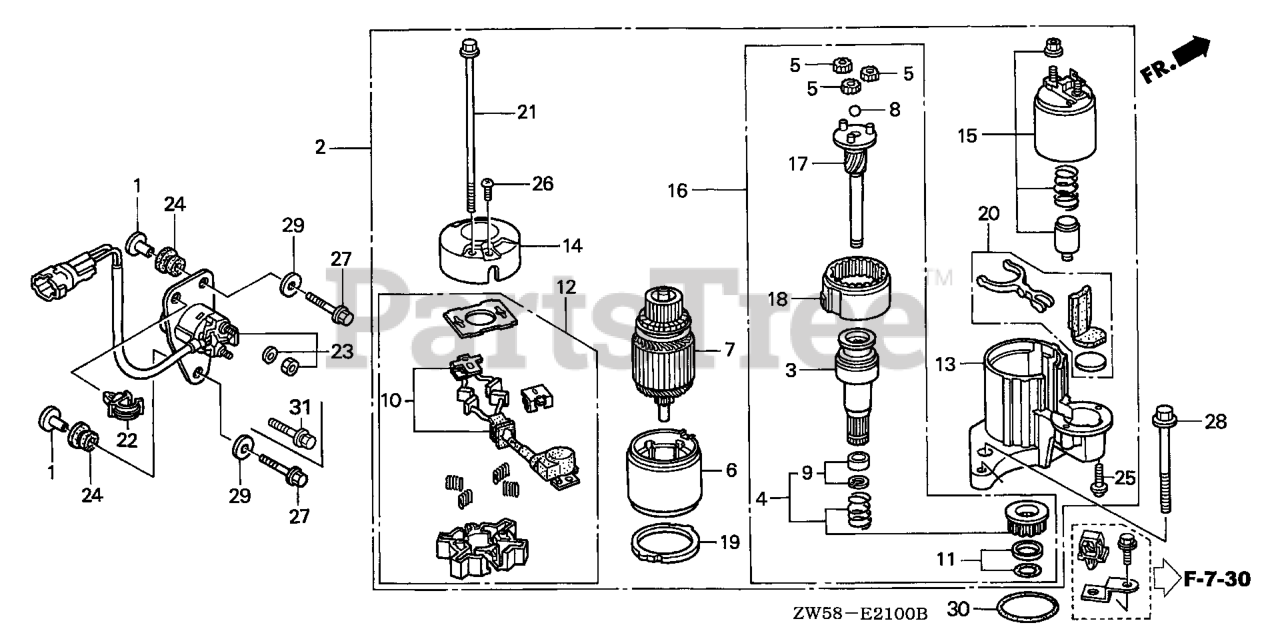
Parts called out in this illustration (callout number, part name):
1	COLLAR, FUEL TANK MOUNTING
2	STARTER MOTOR ASSY.
3	CLUTCH, OVERRUNNING
4	GEAR SET, PINION
5	GEAR ASSY., PLANETARY
8	BALL, STEEL
9	STOPPER SET, PINION
11	STOPPER SET, SLEEVE
12	HOLDER, BRUSH
13	BRACKET, FR.
14	BRACKET, RR.
15	SWITCH ASSY., MAGNET
16	SHAFT ASSY., CLUTCH
17	SHAFT ASSY., GEAR
18	GEAR ASSY. (INNER)
21	BOLT A, THROUGH
22	CLAMP, WIRE
23	SWITCH ASSY., STARTER MAGNETIC
24	RUBBER A, LICENSE BRACKET CUSHION
25	SCREW, PAN (6X22) (SPECIAL)
26	SCREW, PAN (5X8)
27	BOLT, FLANGE (6X25)
28	BOLT, FLANGE (10X35)
29	WASHER, PLAIN (6MM)
30	O-RING (54.4X3.1)
